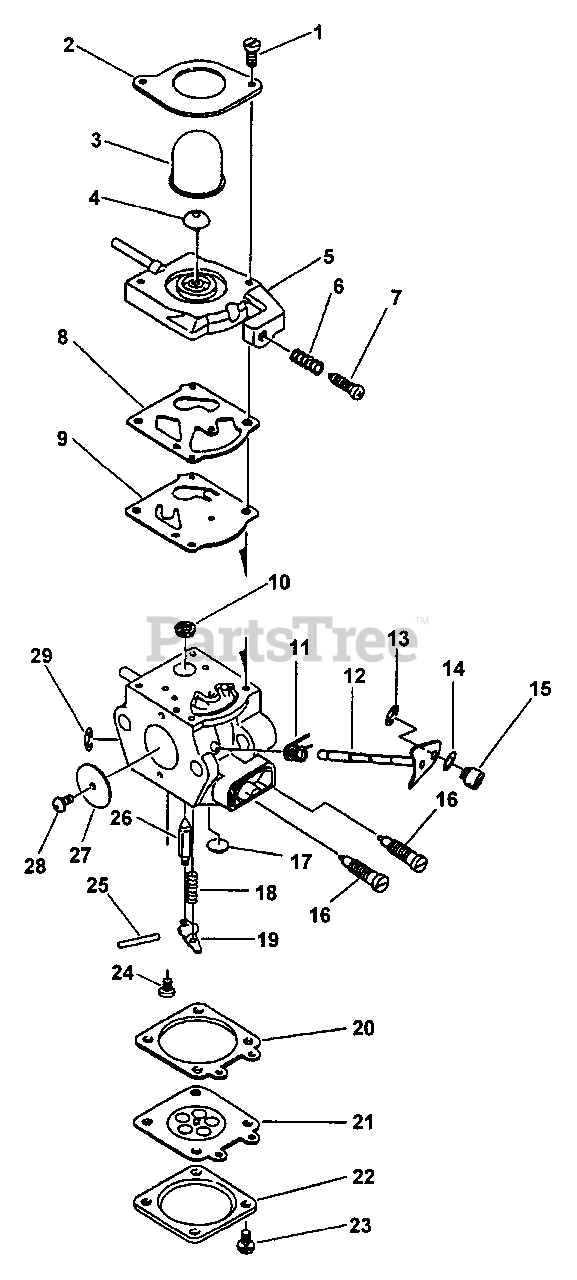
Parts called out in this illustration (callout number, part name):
1	SCREW, PUMP COVER
2	RETAINER, PURGE BULB
3	BULB, PURGE
4	VALVE, CHECK
5	BASE, PURGE
6	SPRING, IDLE ADJUST
7	SCREW, IDLE ADJUST
8	GASKET, PURGE
9	DIAPHRAGM, PURGE
10	STRAINER
11	SPRING, THROTTLE RETURN
12	SHAFT, THROTTLE
13	RING, RETAINING
16	NEEDLE - MIXTURE
17	PLUG, WELCH
18	SPRING, METERING LEVER
19	LEVER, METERING
20	GASKET, METERING
21	DIAPHRAGM, METERING
22	COVER, METERING
23	SCREW
24	SCREW
25	PIN, METERING LEVER
26	VALVE, INLET NEEDLE
27	VALVE, THROTTLE
29	RING, RETAINING
